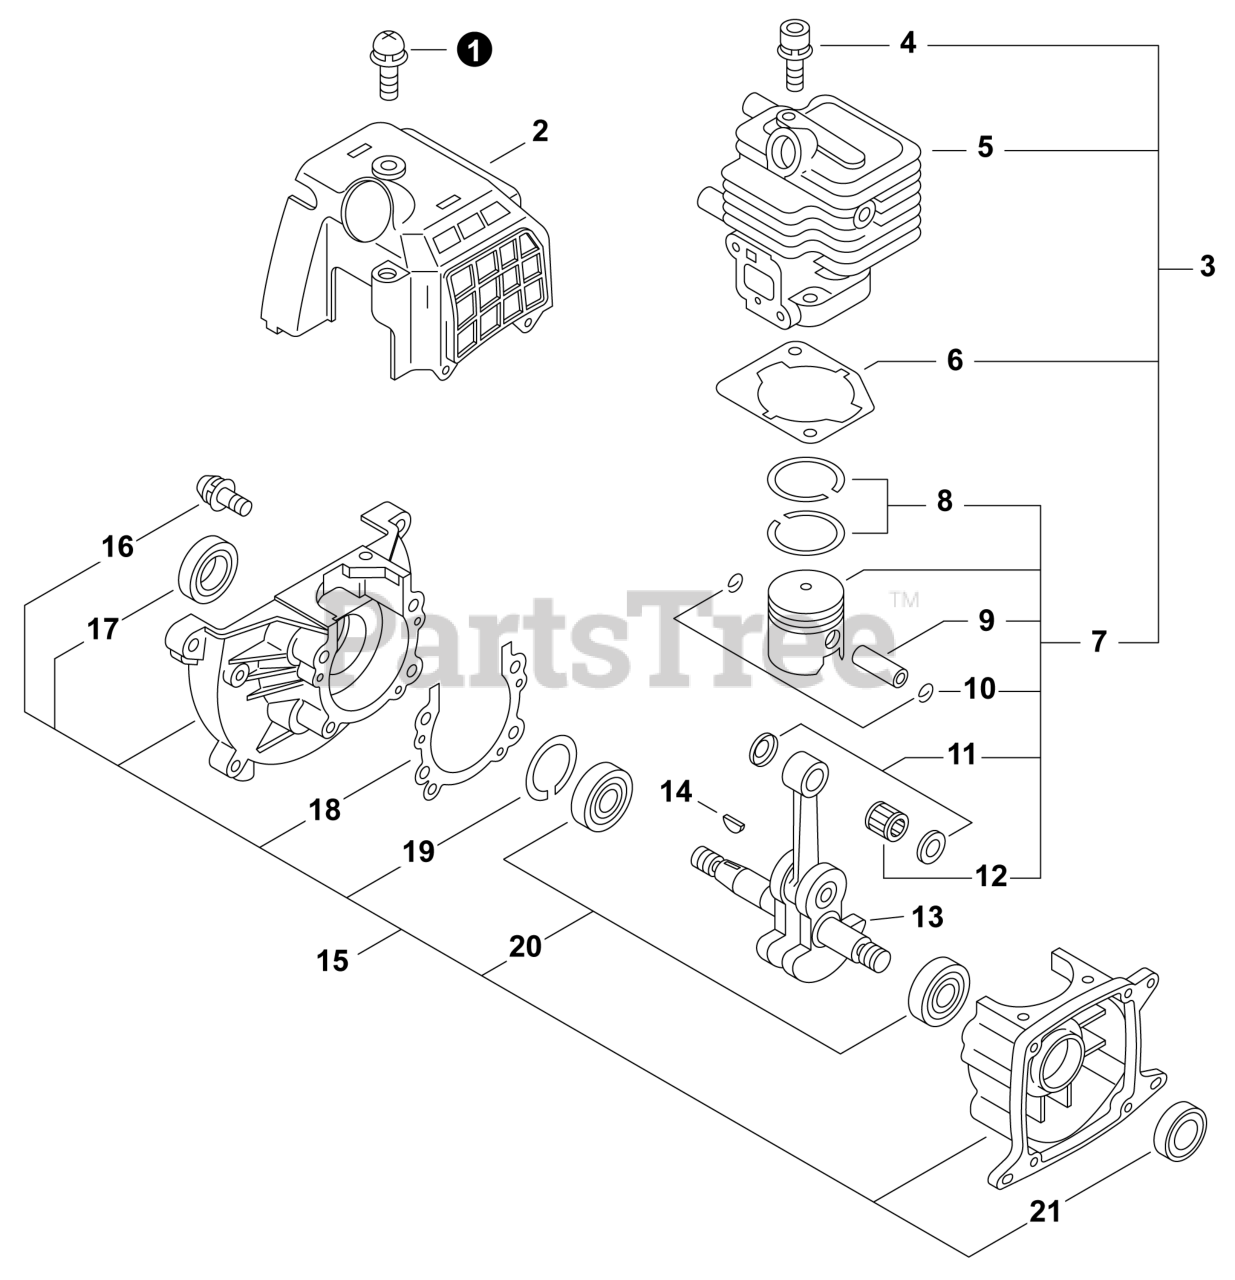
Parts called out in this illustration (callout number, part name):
1	SCREW 5x14
2	COVER, CYLINDER
3	REPAIR KIT, ENGINE
4	BOLT 5x22
5	CYLINDER
6	GASKET, CYLINDER
7	PISTON KIT
8	RING, PISTON
9	PIN, PISTON
10	RING, SNAP
11	WASHER, THRUST
12	BEARING, NEEDLE 8
13	CRANKSHAFT
14	KEY, WOODRUFF
15	CRANKCASE KIT
16	SCREW 5x25
17	SEAL, OIL 12
18	GASKET, CRANKCASE
19	RING, SNAP 28
20	BEARING, BALL 6001
21	SEAL, OIL 12
